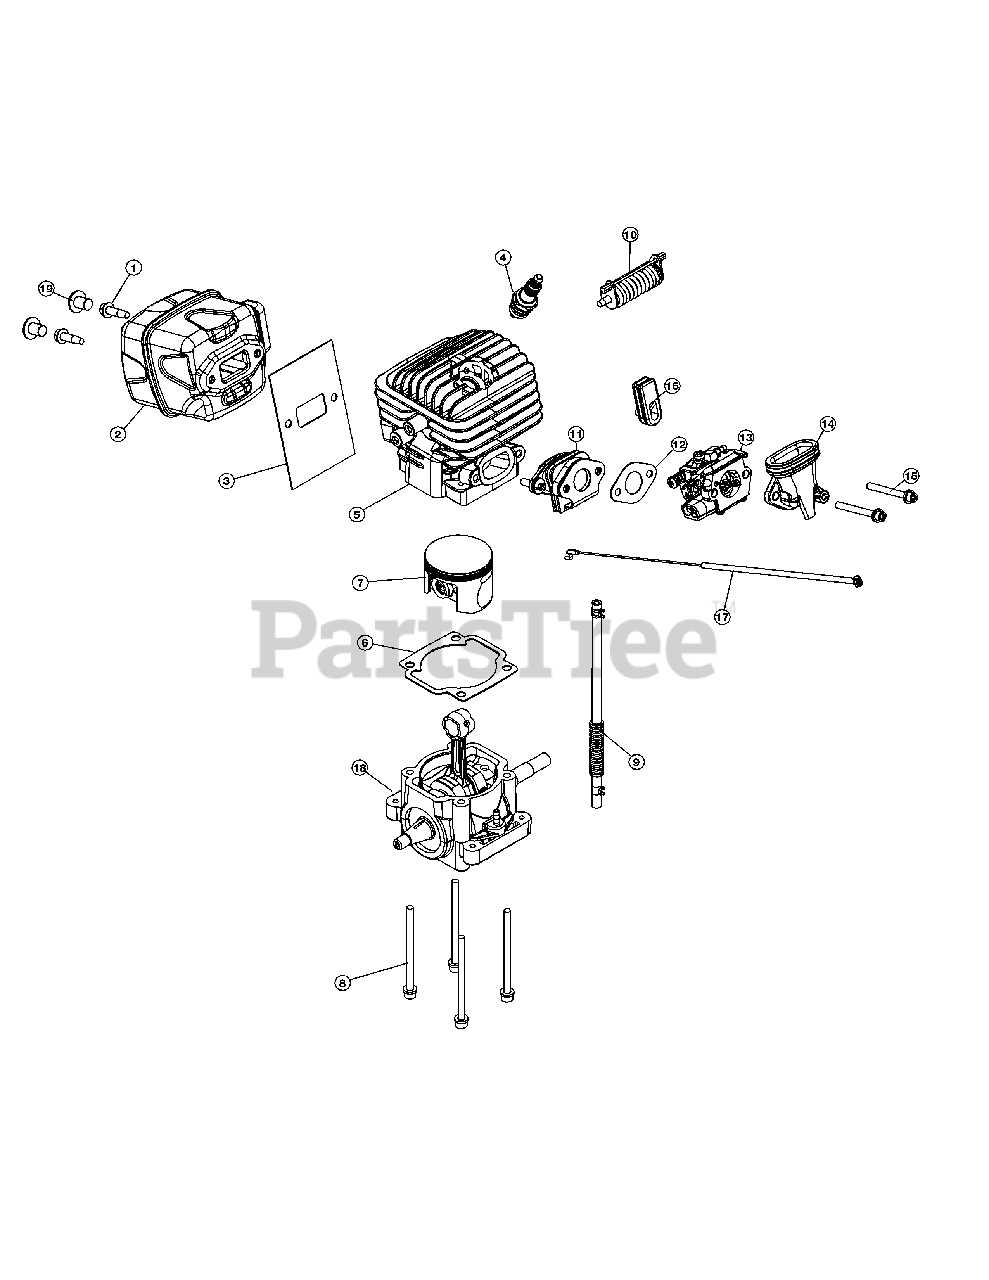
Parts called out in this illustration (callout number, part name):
1	Muffler Screw
2	Muffler Assembly (Incl. 1, 3 & 19)
3	Muffler Gasket
4	Spark Plug
5	Cylinder Assembly
6	Cylinder Gasket
7	Piston Assembly
8	Cylinder Hardware Kit (4 screws)
9	Breather Hose w/clamp
10	Isolator Assembly
11	Insulator Assembly
12	Carburetor Gasket
13	Carburetor
14	Boot, Bracket & Cable Assembly (Incl. 16 & 17)
15	Carburetor Hardware Kit (2 screws)
16	Grommet
17	Throttle Cable
18	Shortblock Assembly (Incl. 2-10)
19	Muffler Plug
